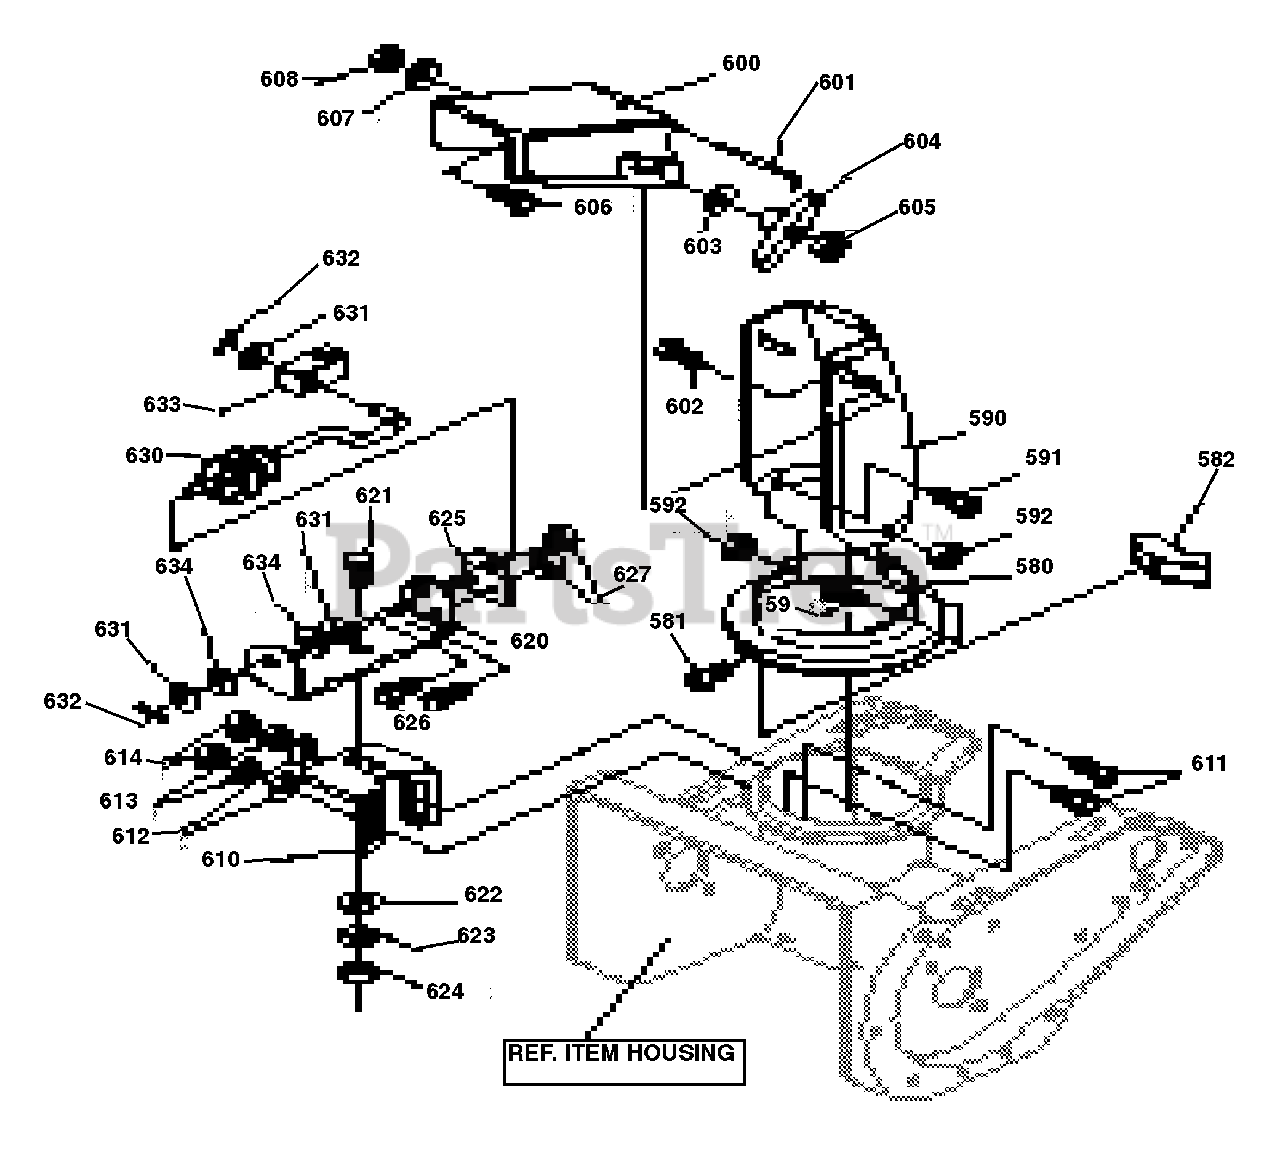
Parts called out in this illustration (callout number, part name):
580	RING, LOWER CHUTE
581	SCREW, 1/4-14 X .63
582	CLIP, CHUTE RING
590	CHUTE, LOWER
591	SCREW, 1/4-20 X .50
600	CHUTE, UPPER
601	WIRE, HINGE
602	BOLT, 5/16-18 X 1.25
603	WASHER, FLAT
604	KNOB, T
605	NUT, 5/16-18
606	SCREW, 5/16-18 X .75
607	WASHER, FLAT
610	BRACKET, WORM ADJUST
611	BOLT, 5/16-18 X .75
614	NUT, 5/16-18 REGHEX
620	BRACKET, CHUTE ROD HOLDER
621	BOLT, 5/16-18 X .75 CARR
622	WASHER, FLAT
623	WASHER, HVSPTLK
624	NUT, 5/16-18 REGHEX
625	PLATE, CHUTE ROD
626	SCREW, 1/4-20 X .50
627	NUT, 1/4-20 REGHEXCTRLK
630	ROD, ASSY CHUTE LOWER
631	WASHER, FLAT
632	PIN, COTTER .090 DIA X .75
633	BLOCK, PIVOT
634	WASHER, CURVED SPRING
